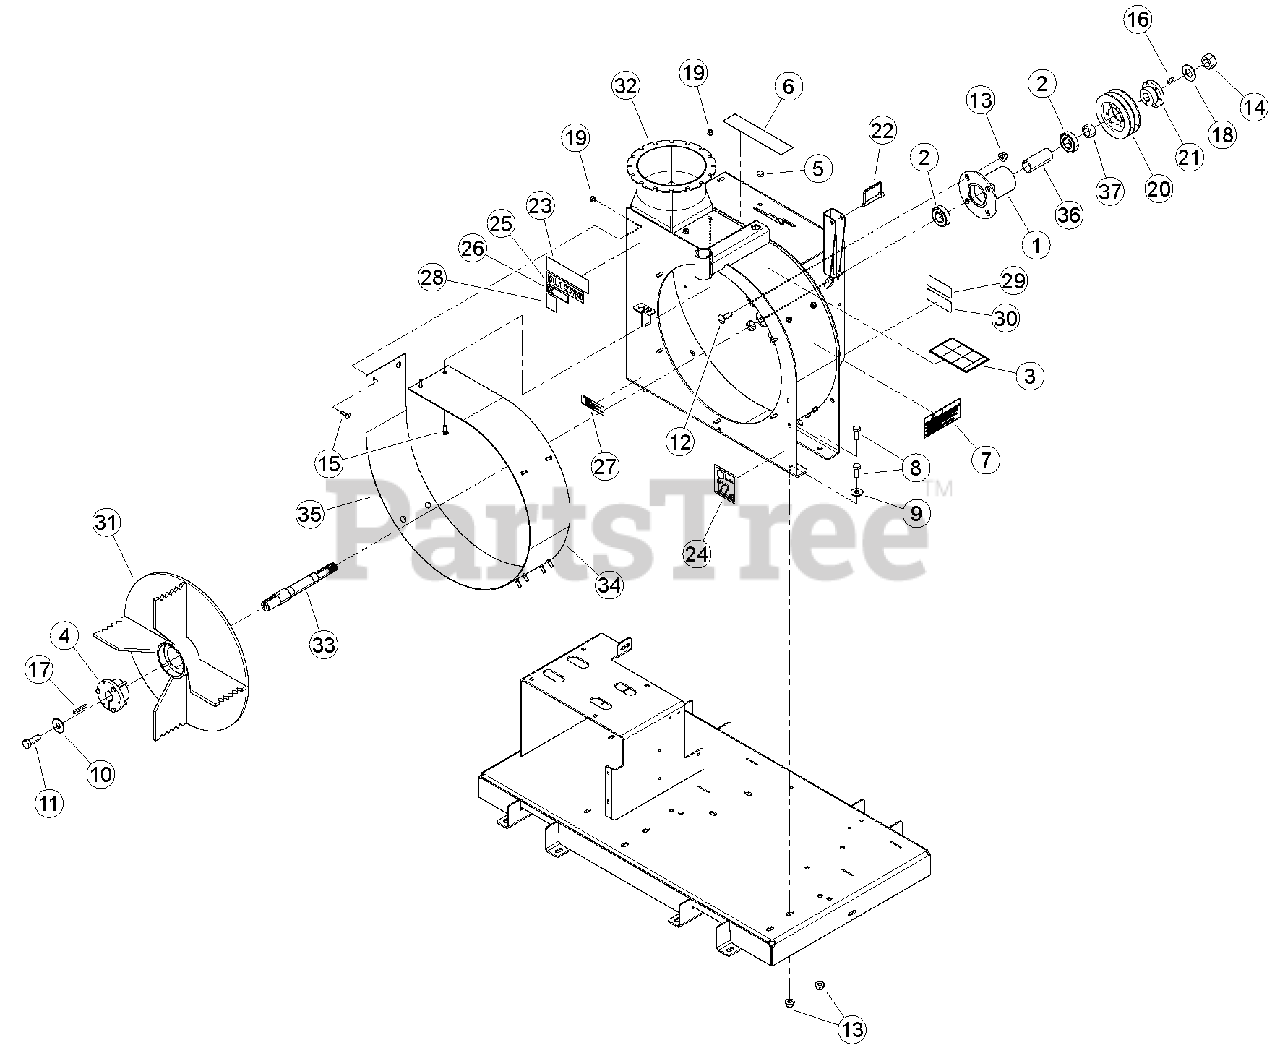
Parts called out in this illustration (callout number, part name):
1	BEARING, HUB (MACHINED)
2	BEARING, 30MM
3	DECAL, OPERATING INSTRUCTIONS ISO
4	BUSHING, SK 1-1/4"
5	BUMPER, RUBBER
6	DECAL, ROTOR ENGAGEMENT
7	DECAL, MUTILINGUAL MANUAL
8	BOLT, 1/2 X 1-1/4" GR5 HHCS NC ZP
9	WASHER, 1/2" FLAT ZP
10	WASHER, 5/8" FLAT ZP
11	BOLT, 5/8 X 1-3/4 G5 NF HX CAP ZP
12	BOLT, 1/2 X 1-1/2" GR5 CRG ZP
13	NUT, 1/2-13 NYLOCK FLANGE
14	NUT, 1" CENTERLOCK NC ZP
15	BOLT, 5/16 X 1" GR5 CRG ZP
16	KEY, 1/4" SQ X 1" LG
17	KEY, 1/4" SQ X 2" PLAIN
18	WASHER, 1" SAE FLAT ZP
19	NUT, 5/16-18 NYLOCK-FLANGE
20	SHEAVE, 2B5.2 SDS
21	BUSHING, SDS 1"
22	PIN, 3/8 X 2-3/4" SNAP
23	DECAL, ECHO BEARCAT 6.82 X 1.90
24	DECAL, 122 DB
25	DECAL, MODEL DL12720
26	DECAL, DL12720 INFORMATION
27	DECAL, ATLANTIC BRIDGE LTD INFO
28	DECAL, ECHO BEARCAT QR CODE
29	DECAL, EPA EVAP
30	DECAL, CARB EVAP
31	WELDMENT, FAN "BEAR CLAW"
32	WELDMENT, FAN HOUSING
33	SHAFT, VACUUM FAN
34	WRAP, HOUSING FAN
35	WRAP, HOUSING FAN
36	SPACER, BEARING HUB
37	SPACER, 1-1/2 X 11/16
